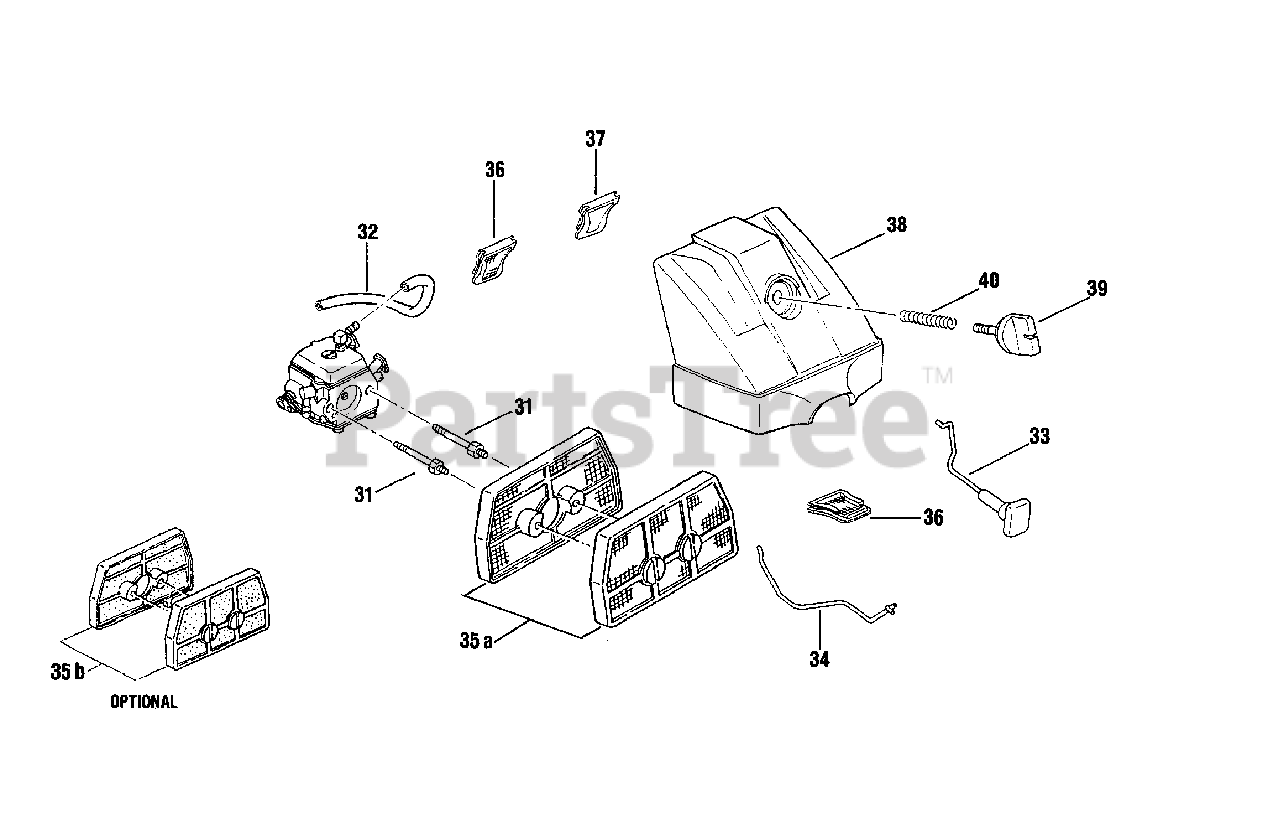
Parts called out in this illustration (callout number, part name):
31	CARBURETOR BOLT
32	PIPE, PULSE
33	ROD, CHOKE
34	ROD, THROTTLE
35A	AIR FILTER ASSY - STAINLESS
35B	FILTER, AIR - FLOCKED
36	PRE-FILTER
37	PLUG
39	KNOB, FILTER COVER
40	SPRING
